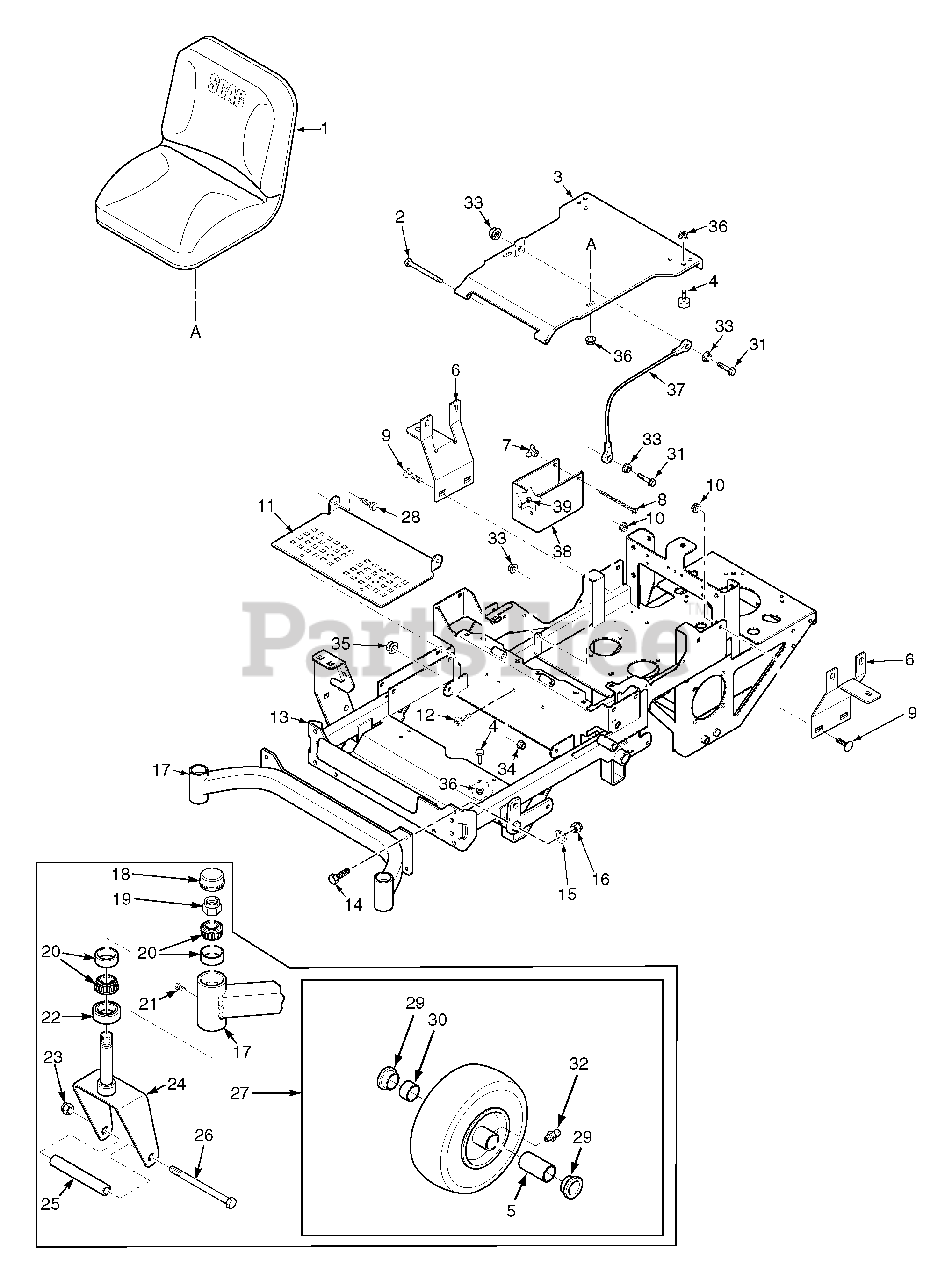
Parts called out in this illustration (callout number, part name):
1	Seat Assembly
2	Bolt, Hex Head 3/8-16 x 3-3/4"
3	Seat Mounting Base Weldment
4	Bumper, Rubber
5	Roller Bearing, .625 x 3-1/4"
6	Bracket, Fuel Tank Mounting
7	Wing Nut, 1/4-20
8	Bolt, Carriage 1/4-20 x 6"
9	Bolt, Carriage 5/16-18 x 3/4"
10	Nut, Serr. Flange 5/16-18
11	Foot Plate
12	Bolt, Torx 3/8-16 x 1"
13	Mainframe Weldment
14	Bolt, Hex Head 7/16-14 x 1-1/4"
15	Lockwasher, 7/16"
16	Nut, Elastic Stop 7/16-14
17	Caster Support Weldment - 36"
18	Cap, Grease
19	Nut, Elastic Stop 1"-14 Jam
20	Bearing w/Race
21	Plug, 1/4-28 Self Tap
22	Seal, 2" O.D. x 1.625 I.D.
23	Nut, Elastic Stop 1/2-13
24	Caster Yoke Weldment
25	Sleeve, Caster Wheel
26	Bolt, Hex Head 1/2-13 x 6-1/2"
27	Caster Wheel Assy.
28	Bolt, Hex Head 3/8-16 x 1"
29	Bearing, Oilite
30	Roller Bearing, .625 x 1"
31	Bolt, Hex Head 1/4-20 x 1-1/4"
32	Grease Fitting, 1/4-28 Straight
33	Nut, Serr. Flange 1/4-20
34	Nut, Elastic Stop 5/16-18
35	Nut, Elastic Stop 3/8-16
36	Nut, Serr. Flange 5/16-18
37	Cable, Seat Stop
38	Battery Box
39	Nut, Serr. Flange 3/8-16
